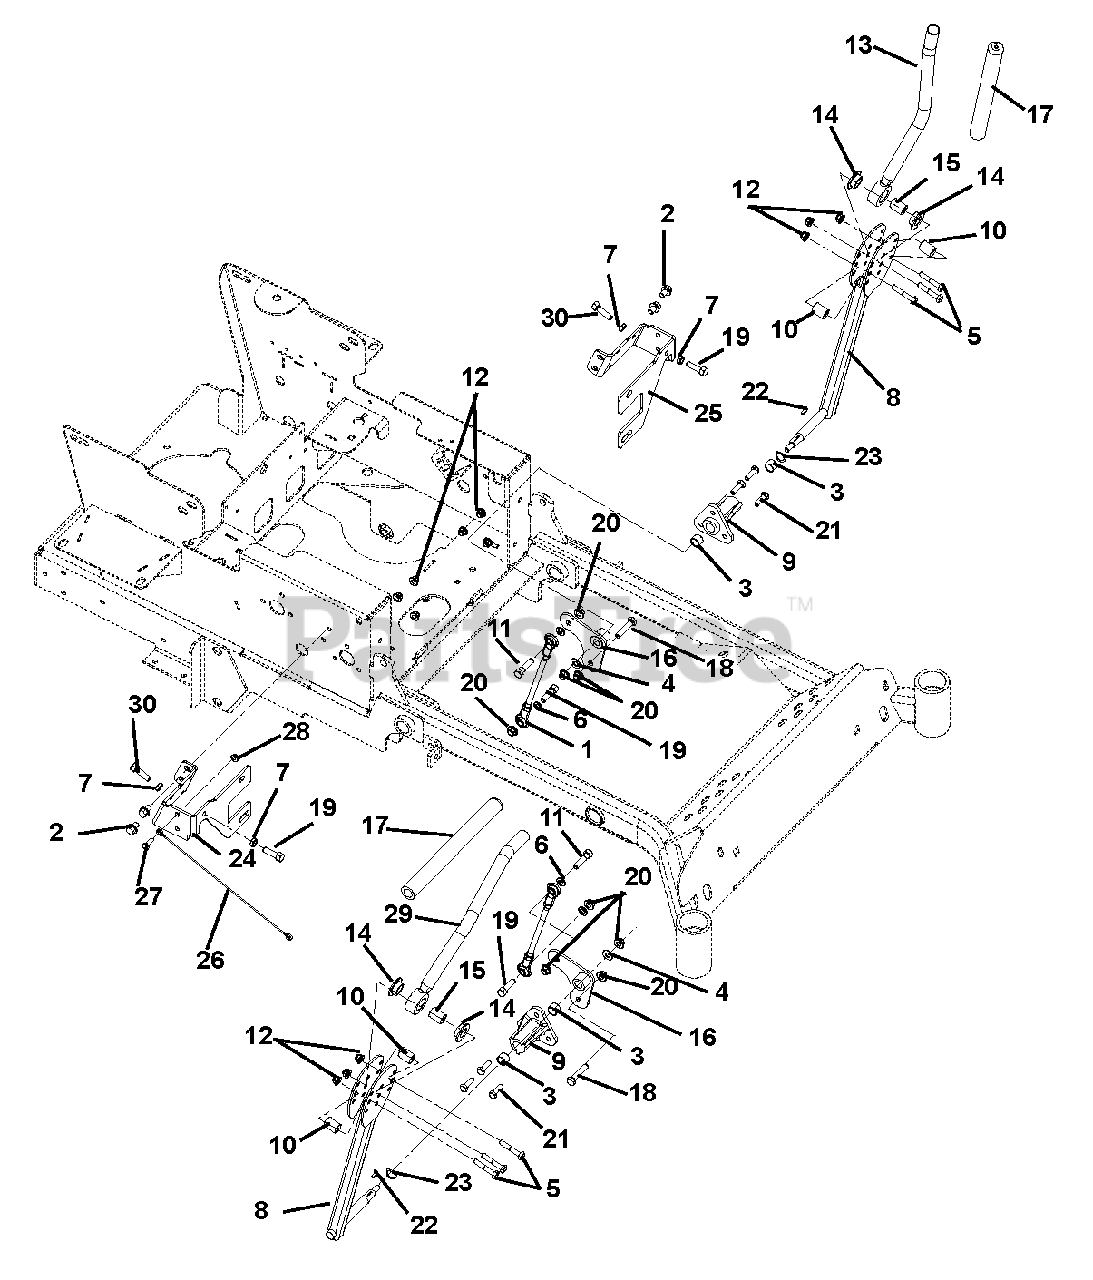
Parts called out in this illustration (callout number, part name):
1	ASM, STEERING LINKAGE
2	@SCR-TAP .38-16X.50 HWH TR YWZ
3	BSHG .625X.750X.500
4	@WSHR-FL-STL.406X.812X.065 YWZ
5	@BLT-HEX .31-18X1.75 GR5 YWZC
6	@WSHR-LK .38X.094 REG YWZC
7	NUT-HEX-JAM .375-16 YWZC
8	CONTROL ARM - BLACK
9	BUSHING, FLANGE
10	ECCENTRIC
11	@BLT-HEX .38-16X1.50 GR5 YWZC
12	@NUT-LK-NYL-FLG .31-18 YWZC
13	HANDLE WLDMT LH
14	BSHG-FLG .762X1.48X.44 NYL
15	SPACER .328 X .76 X 1.01
16	WMT, TRANSMISSION CONTROL ARM
17	GRIP, HANDLEBAR
18	BLT-HEX .375-16X1.750 FTD YWZC
19	@BLT-HEX .38-16X1.25 GR5 YWZC
20	@NUT-LK-NYL-FLG .38-16 YWZC
21	@BLT-HEX .31-18X1.00 GR5 YWZC
22	KEY-WDRF .13X.63 HRD#5
23	WAVE WASHER .640X.875X.125FH
24	STOP, STEERING-RH (BLACK)
25	STOP, STEERING -LH (BLACK)
26	CABLE, 12.0 LANYARD, NYLON
27	@BLT-HEX .25-20X.75 GR5 YWZC
28	@NUT-LK-NYL-FLG .25-20 YWZC
29	WLDMT, RH HANDLE
30	@BLT-HEX .38-16X.75 GR5 YWZC
